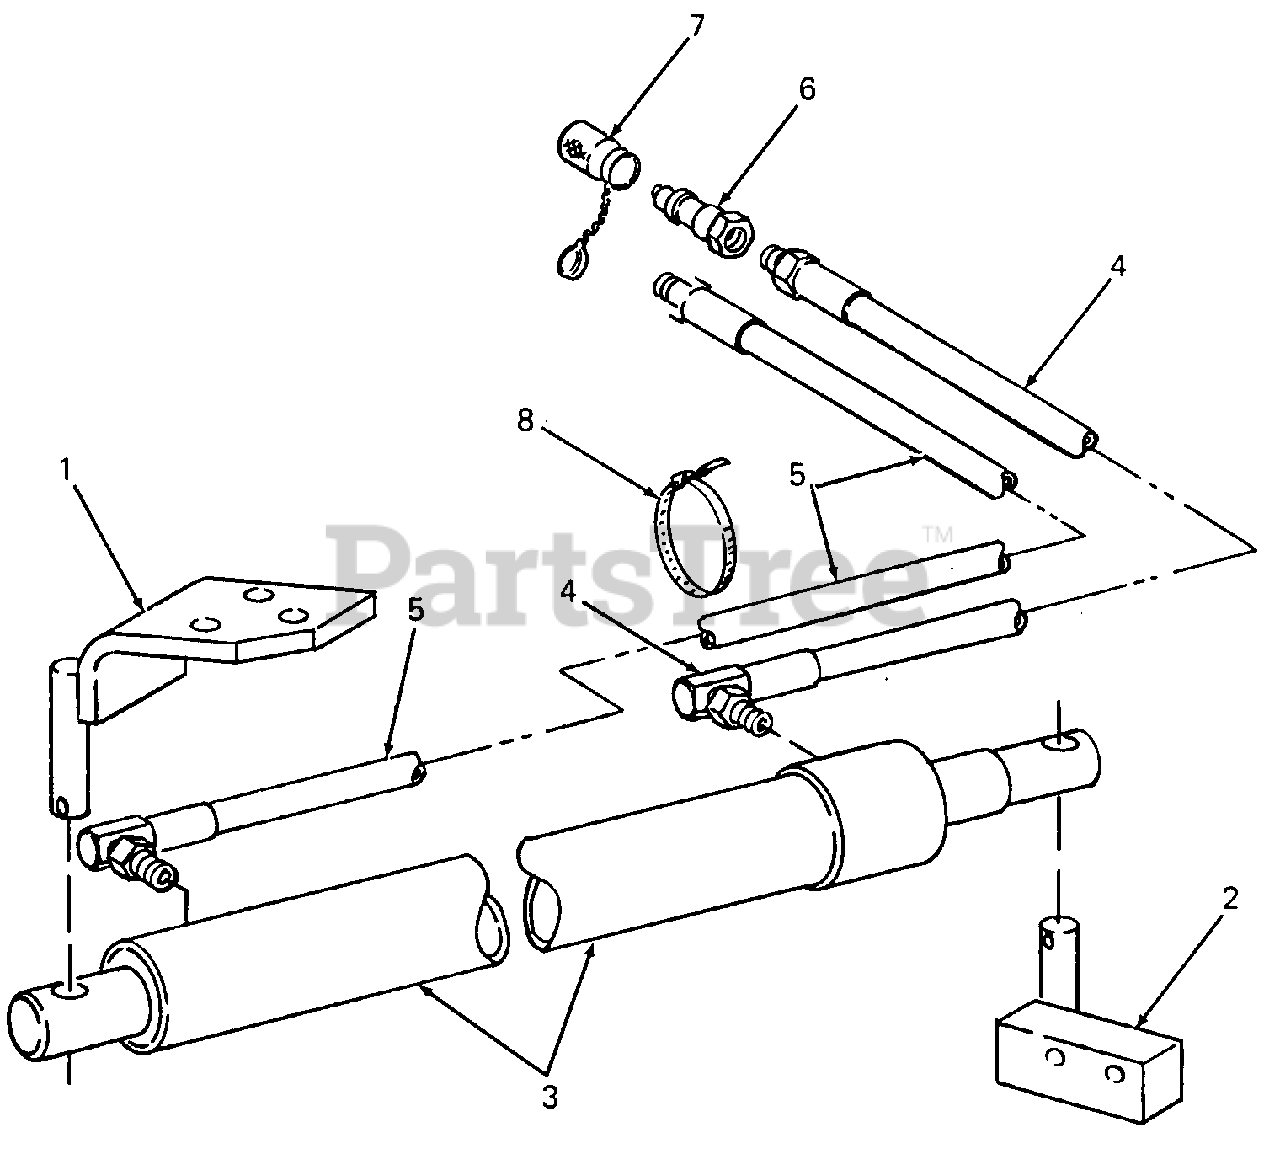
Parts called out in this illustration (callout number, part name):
1	Bracket Assy, Rear
2	Bracket Assy, Front
3	Cylinder, Hydraulic
6	Coupling, Hydraulic Hose
7	Cap, Hydraulic Hose Coupling
8	Strap, Cable Tie
